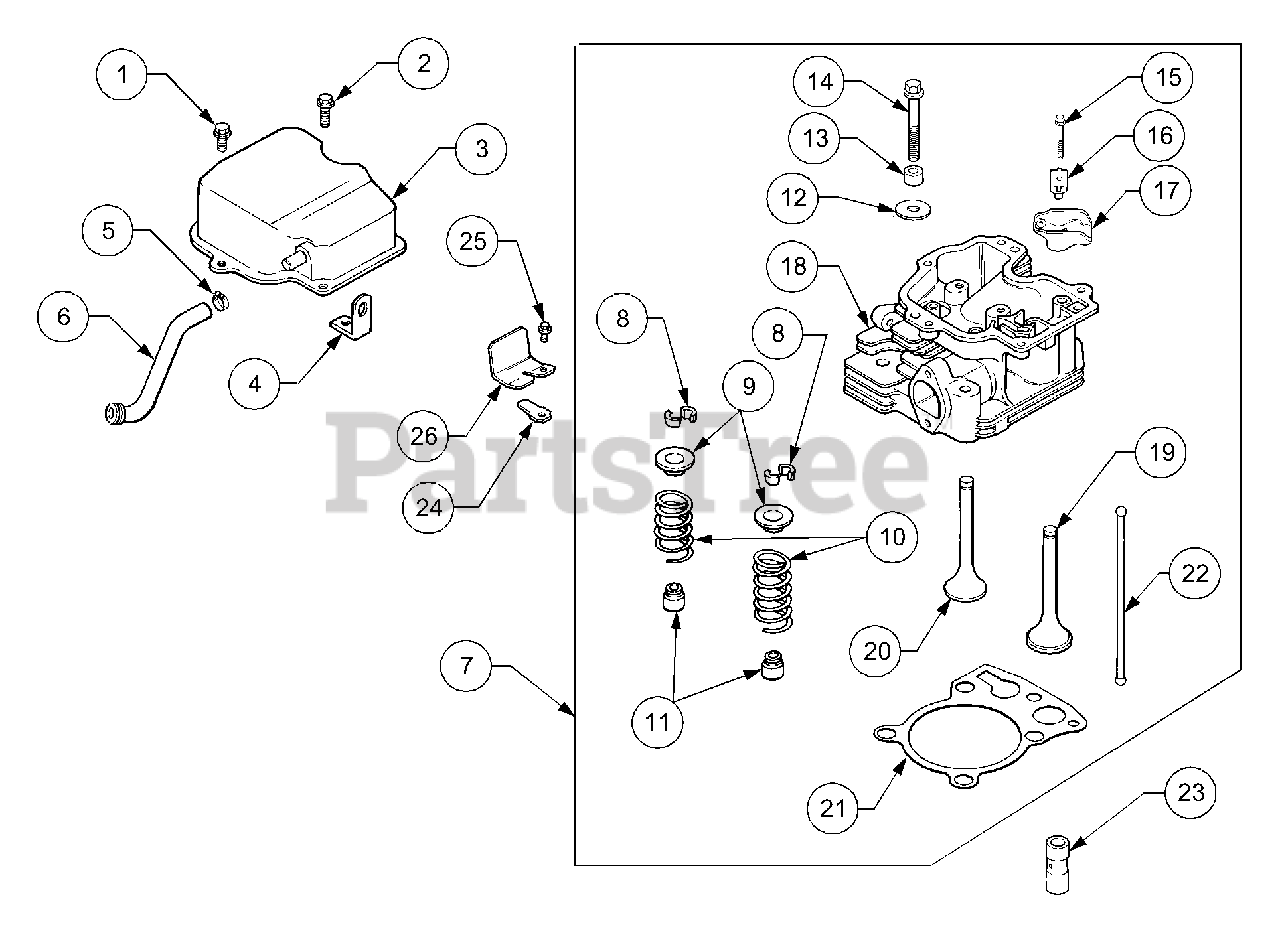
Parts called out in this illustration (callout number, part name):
1	Screw, Hex Flange, M6 x 1 x 16
2	Screw, Hex Flange, M6 x 1 x 20
3	Cover, Valve w/Nipple
4	Strap, Lifting
5	Clamp, Hose
6	Hose, Breather
7	Kit, Cyl Head,
8	Kit, Retainer
9	Cap, Valve Spring
10	Spring, Valve
11	Seal, Valve Stem
12	Washer, Plain, 13/32"
13	Spacer, Head Bolt Exhaust Port
14	Screw, Hex Flange, M10 x 1.5 x 81
15	Screw, Hex Flange, M6 x 1 x 34
16	Pivot, Rocker Arm
18	Head, Cylinder
19	Valve, Intake (Std.)
20	Valve, Exhaust (Std.)
21	Gasket, Cylinder Head
23	Lifter, Valve
24	Reed, Breather
25	Screw, Hex Flange, M5 x .8 x 10
26	Retainer, Breather Reed
